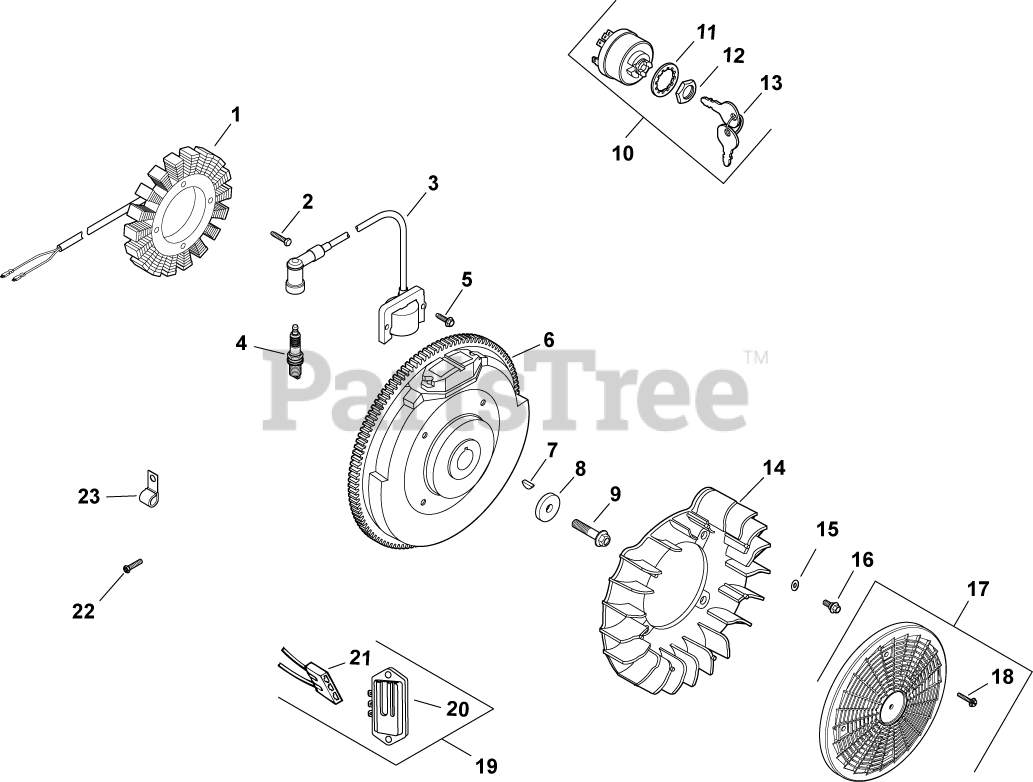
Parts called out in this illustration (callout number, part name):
1	KIT, 25 AMP STATOR ASSY.
2	SCREW, THD FROM M5X0.8X30
3	MODULE, IGNITION
4	PLUG, SPARK (PRO SERIES)
5	SCREW, FLG THD FRM M5X.8X20-(#25086399S)
6	FLYWHEEL ASSEMBLY (LW)-USE 24 025 58-S
7	KEY, 3/16" X 5/8"
8	WASHER, FLAT 13/32"
9	SCREW, FLG M10X1.5X45 - (#25086361S)
10	SWITCH ASSY, KEY (KM)-USE 25 099 32-S
11	WASHER, INTERNAL TOOTH
12	NUT, KEY SWITCH
13	KEY, SET -USE 48 340 01-S
14	FAN USE 24 157 11-S
15	WASHER, FLAT 1/4" (O.D. 1/2")
16	BOLT, SHOULDER
17	KIT, GRASS SCREEN
18	SCREW, FLG SEMS M4X.7X25
19	KIT, FULL WAVE CONVERSION
20	REG/RECTIFIER (20/25 AMP)-USE 25 403 20-
21	CONNECTOR, BODY (KM)-USE 25 155 41-S
22	SCREW, HEX FLANGE HI-LO
23	CLIP, CABLE
2458452-S	MODULE, SPARK ADV -USE 24 584 89-S
